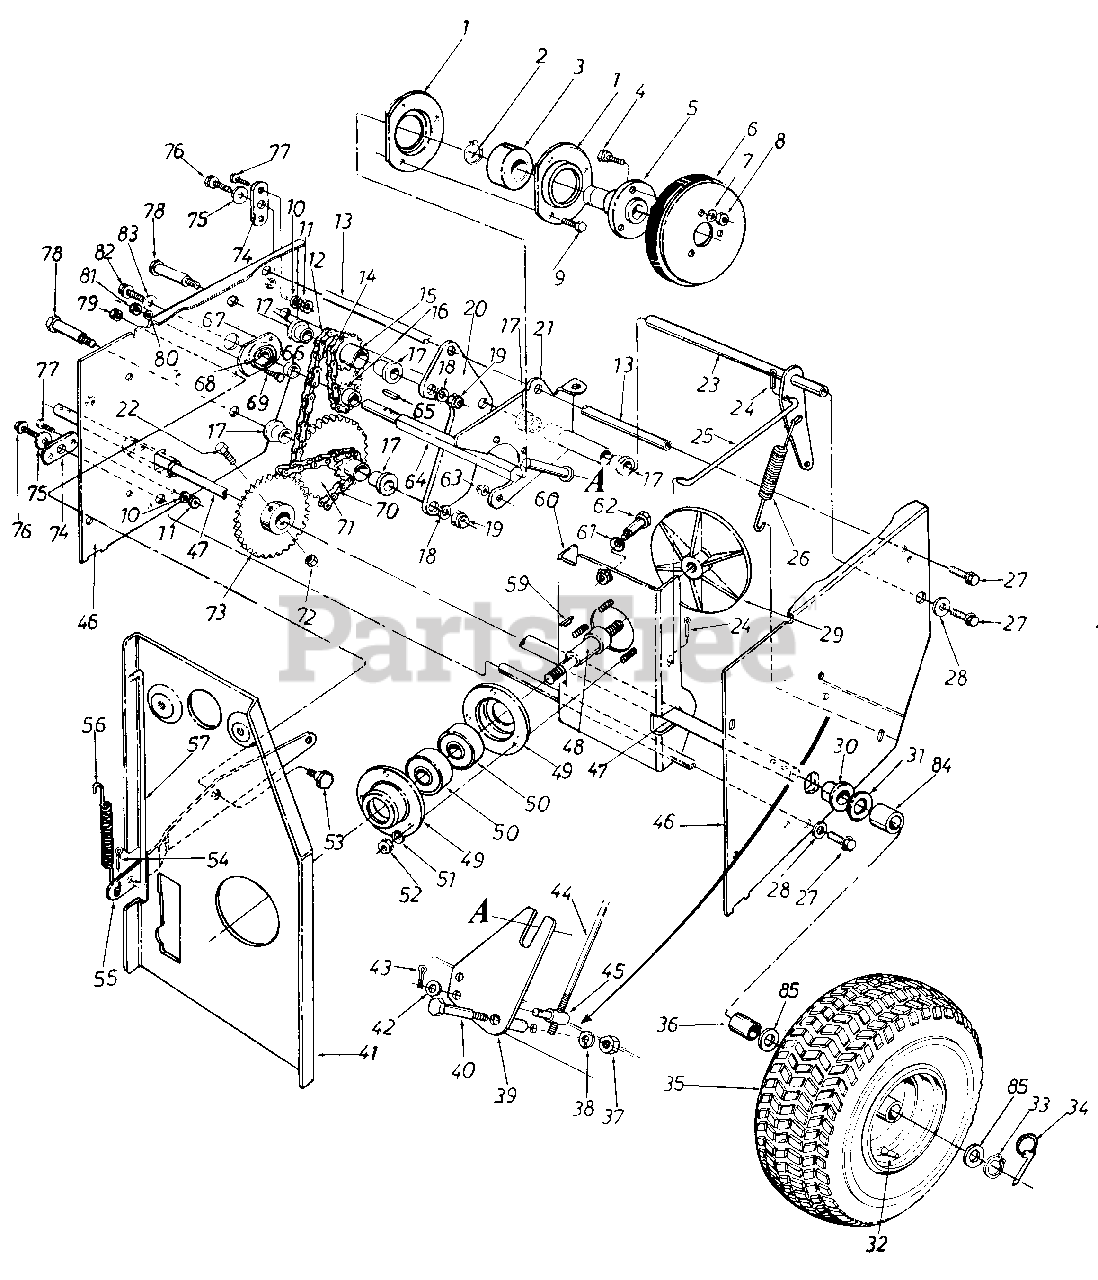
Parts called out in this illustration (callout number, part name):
1	Bearing Housing
2	Snap Ring-1.0" Dia.
3	Ball Brg. .25MM x 52MM x 15MM Thk.
4	Hex Sems Bolt 5/16-18 x .75" Lg.*
5	Friction Wheel Adapter
6	Friction Wheel Ass'y.
7	L-Wash. 5/16" I.D.
8	Hex Nut 5/16-18 Thd.*
9	Hex Bolt 1/4-28 x .62" Lg.*
10	L-Wash 1/4 " I.D.
11	Hex Nut 1/4-20 Thd.*
12	#41 Chain-1/2" Pitch x 43 Links
13	Sliding Support Axle
14	#41 Chain-1/2" Pitch x 19 Links
15	9 and 14 Teeth Sprocket Hub Ass'y.
16	8 Teeth Sprocket
17	Flange Bearing .63" I.D.
18	L-Wash. 3/8" I.D.-H.D.
19	Hex L-Jam Nut 3/8-24 Thd.
22	Hex Bolt 1/4-28 x 1.5" Lg.
23	Drive Clutch Brkt. Ass'y.
24	Inter. Cot. Pin 5116" Dia.*
25	Drive Clutch Rod .31" Dia. x 7.38" Lg.
26	Extension Spring 4.31" Lg.
27	Hex L-Bolt 5/16-18 x .62"
28	Fl-Wash. .345" I.D. x .75" O.D.
29	Aluminum Drive Plate
30	Flange Brg. w/Flats
32	Tubeless Air Valve
33	Snap Ring 3/4" Shaft
34	Klick Pin
35	Wheel Ass'y. Comp. 15 x 6
36	Bearing . 75" 1. D .
37	Hex Jam Nut 3/8-16 Thd.
38	L-Wash. 3/8" I.D.*
41	Engine Brkt. Ass'y.
42	Fl-Wash. .344" I.D. x .62" O.D.
43	Cotter Pin 3/32" Dia. x .75" Lg.*
44	Shifting Rod
45	Adjustment Ferrule
46	Frame Ass'y.
47	Free Wheeling Axle
48	Drive Plate Spindle
49	Bearing Housing
50	Ball Brg. .787" I.D. x 1.85" O.D.
51	L-Wash. 5/16" I.D.*
52	Hex Nut 5/16-18 Thd.*
53	Shld. Bolt .625" Dia. x .170" Lg.
54	Inter. Cotter Pin 5/16" Dia.
55	Auger Clutch Brkt.
56	Extension Spring .38" O.D. x 3.18" Lg.
57	Auger Clutch Rod .31" Dia. x 10.62" Lg.
59	#61 Hi-Pro Key 3/16" x 5/8" Dia.
62	Shld. Bolt
63	Hex Ins. Jam Nut 1/4-28 Thd.
65	#9 Hi-Pro Key 3/32" x 5/8" Dia.
66	Spacer .51" I.D. x .69" O.D.
67	Bearing Housing
68	Ball Bearing
69	Hex Bolt 1/4-20 x .62" Lg.
70	#420 Chain .50" Pitch x 29 Links
71	9 and 32 Teeth Sprocket Hub Ass'y.
72	Hex L-Nut 1/4-20 Thd.
73	22 Teeth Sprocket Hub Ass'y.
74	Pivot Axle Brkt.
75	Fl-Wash. .345" I.D. x .75"
76	Hex L-Bolt 5/16-18 x .62"
77	Hex Bolt 1/4-20 x .62" Lg.*
78	Sprocket Hub Tubing 1.88"
79	Hex Cent. L-Nut 3/8-16 Thd.
80	L-Wash. 1/4" I.D.
81	Hex Nut 1/4-20 Thd.*
82	Hex L-Bolt 5/16-18 x .62"
83	Fl-Wash. .345" I.D. x .75"
84	Spacer.75" I.D.
